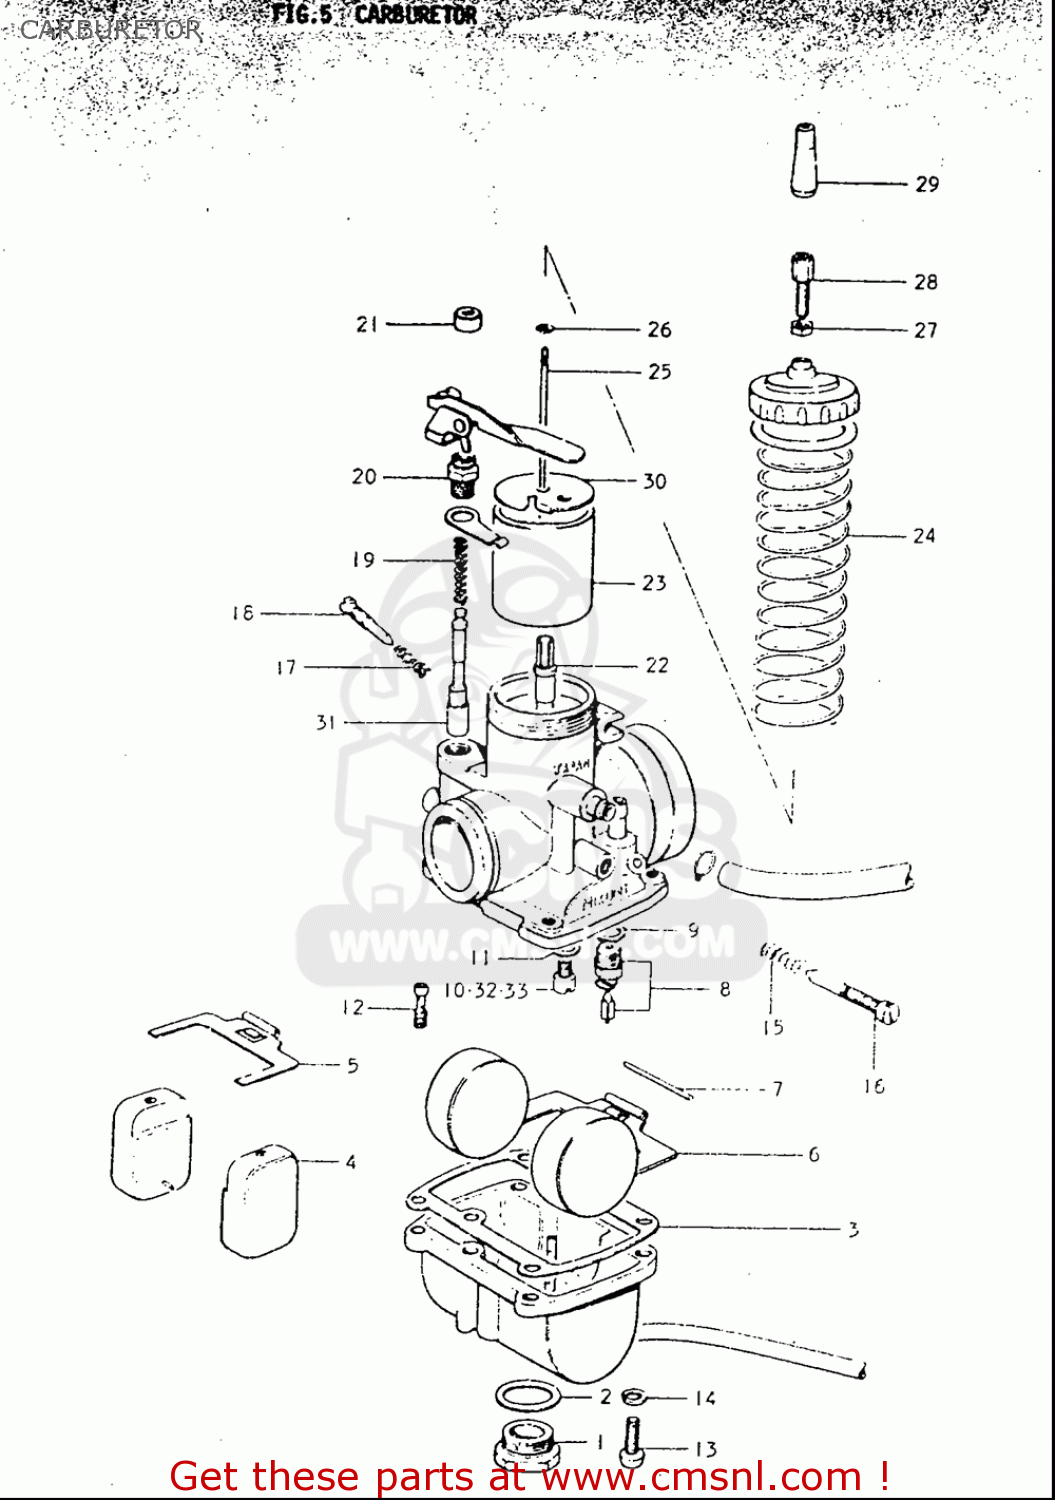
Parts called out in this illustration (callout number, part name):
2	GASKET,DRAIN PLUG
4	FLOAT
8	VALVE ASSY,NEEDLE
9	GASKET,MAIN JET HOLDER (NAS)
10	JET,MAIN(115)
11	WASHER
12	JET,PILOT(25)
13	SCREW
14	WASHER,LOCK
15	SPRING,THROTTLE SCREW
16	SCREW,THROTTLE STOP
17	SPRING
18	SCREW,PILOT AIR
19	SPRING
20	HOLDER,GUIDE
21	CAP,PLUNGER
26	CLIP
27	NUT
28	ADJUSTER,CABLE
29	CAP,RUBBER
31	PLUNGER,STARTER
32	JET,MAIN(120)
33	JET,MAIN(105)
